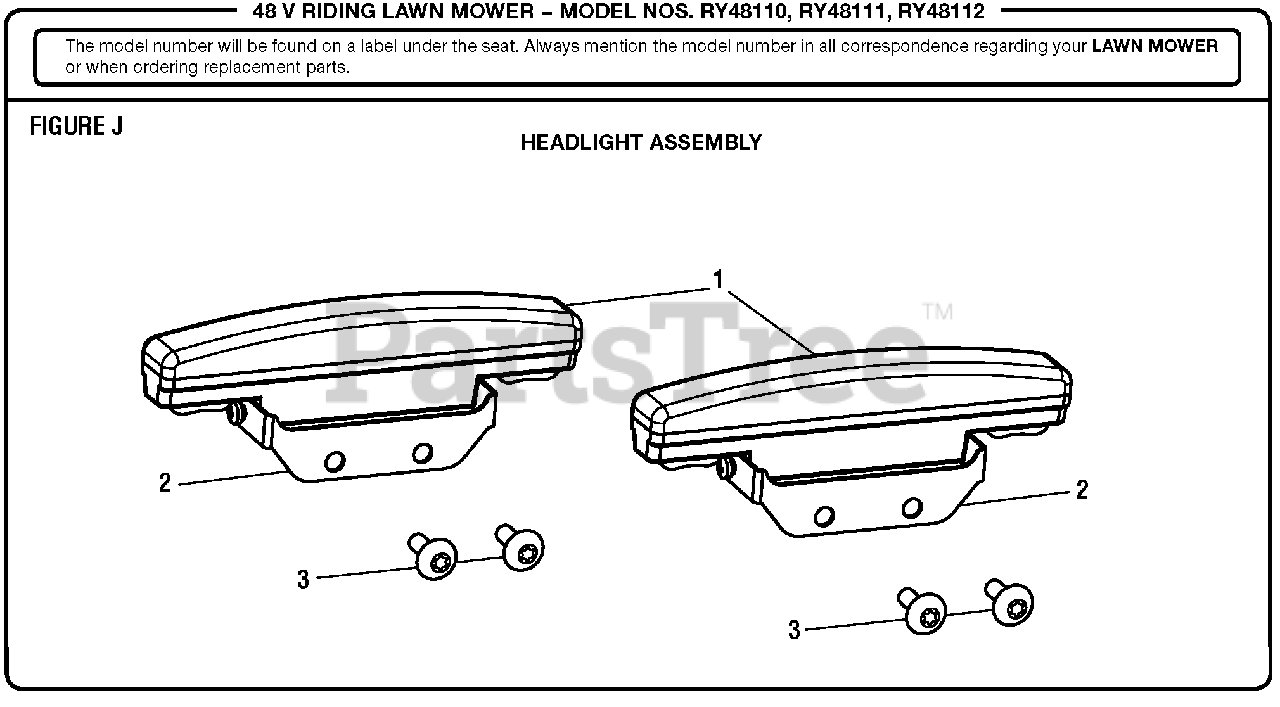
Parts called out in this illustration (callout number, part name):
1	Light Assembly
2	Bracket (Bracket Only)
3	Screw (M6 x 16, Torx. Pan Hd.)
